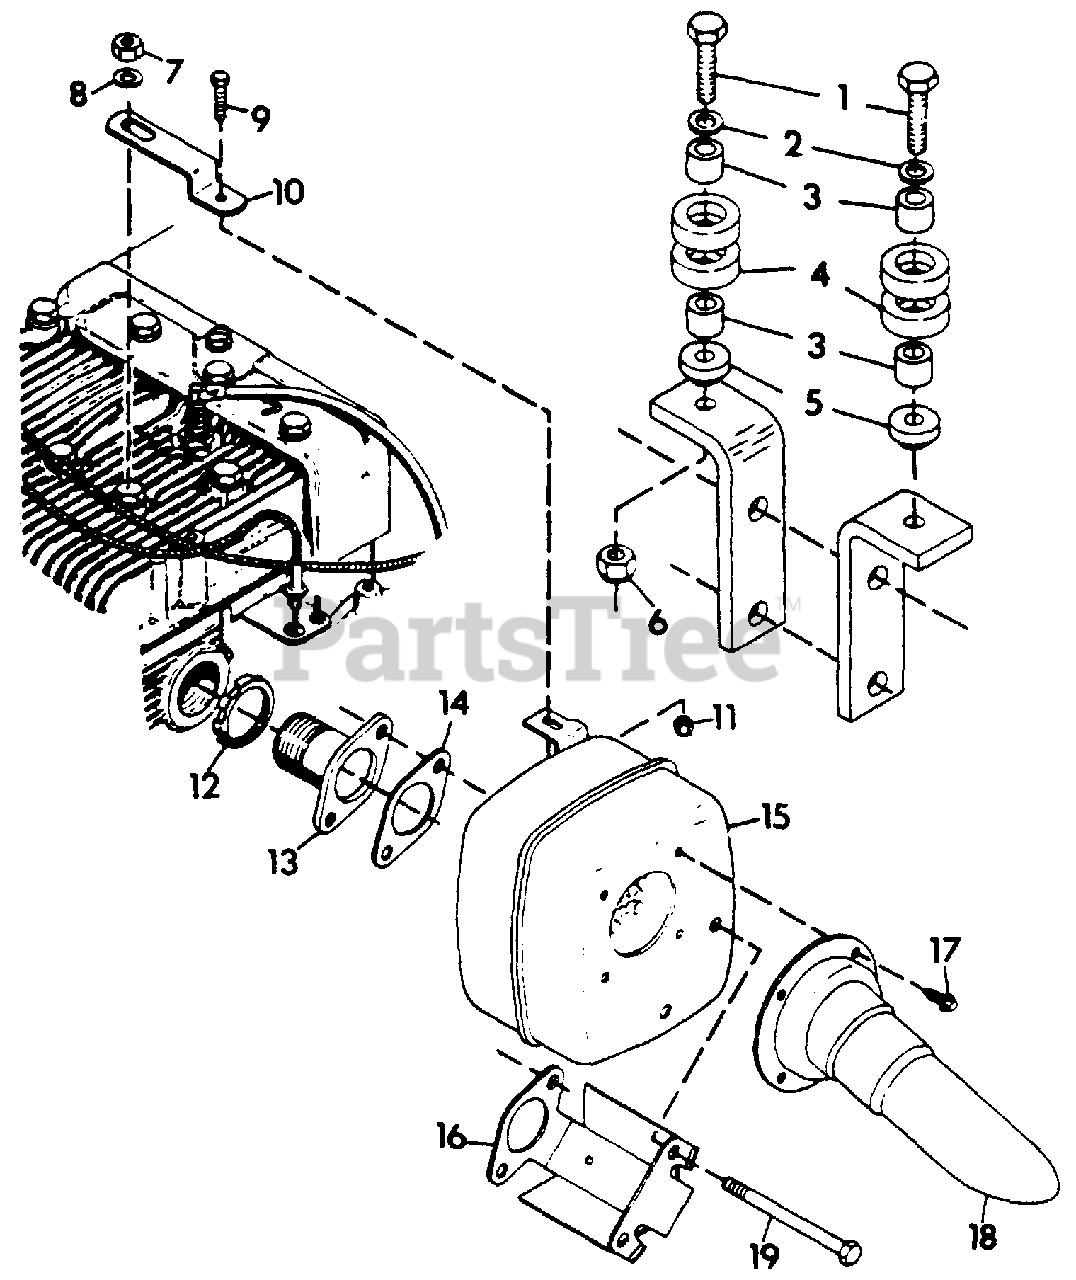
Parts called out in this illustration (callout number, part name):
1	BOLT, HEX 1/4-20X2-1/4
2	WASHER, FLAT .312X.734X.065
3	BUSHING, .259X.375X.25
4	BUMPER, SEAT
5	PIVOT, HOOD
6	NUT, LOCK 1/4-20
7	NUT, HEX 5/16-18
8	WASHER, FLAT .344X.688X.065
9	BOLT, HEX 1/4-20X.750
10	BRACKET, MUFFLER
11	NUT, LOCK 1/4-20
12	NUT, CONDUIT 1" PIPE
13	WELDMENT, MUFFLER ADAPTER
14	GASKET
15	MUFFLER
16	SHIELD, MUFFLER
17	SCREW, TAPPING
18	WELDMENT, MUFFLER DEFLECTOR
19	BOLT, HEX SHOULDER
NS	STUD, MUFFLER BRACKET
